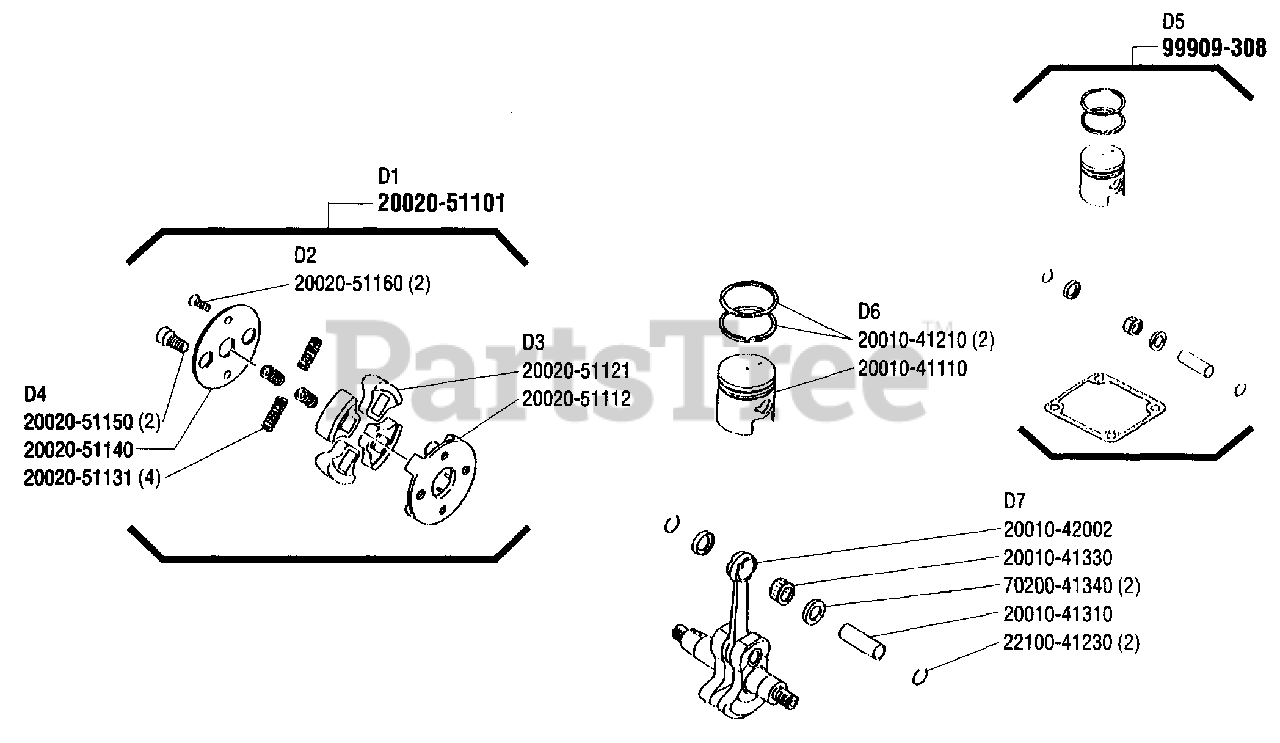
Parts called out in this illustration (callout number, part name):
D1	CLUTCH SHOE ASSY
D2	SCREW
D3	BOSS, CLUTCH
D3	SHOE, CLUTCH
D4	SPRING, CLUTCH
D4	PLATE, CLUTCH
D4	BOLT, CLUTCH
D5	PISTON ASSY
D6	PISTON
D6	RING, PISTON
D7	PIN, PISTON 10
D7	BEARING, NEEDLE 10
D7	CRANKSHAFT ASSY
D7	RING, SNAP
D7	WASHER, THRUST
